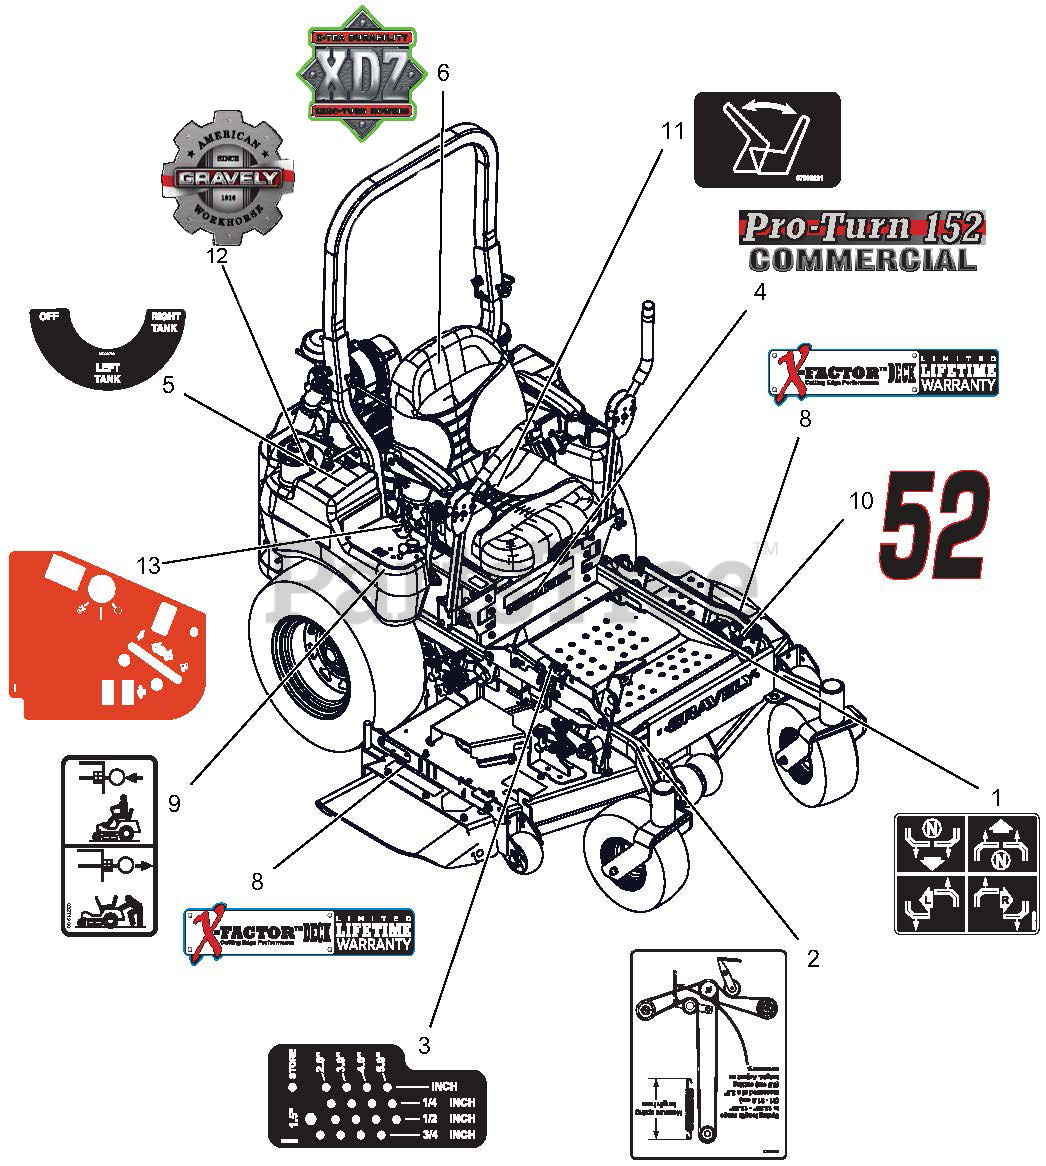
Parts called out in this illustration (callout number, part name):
1	DECAL, INSTRUCTIONAL - STEERING
2	DECAL, BELT ROUTING
3	DECAL, HEIGHT OF CUT
4	DECAL, PRO-TURN 152
5	DECAL, FUEL VALVE
6	DECAL, XDZ
8	DECAL, X-FACTOR DECK
9	DECAL, TRANSMISSION DISCONNECT
10	DECAL, 52"
11	DECAL, SEAT RELEASE
12	DECAL, GRAVELY HERITAGE-LARGE
13	PANEL, PT100 CONTROL
